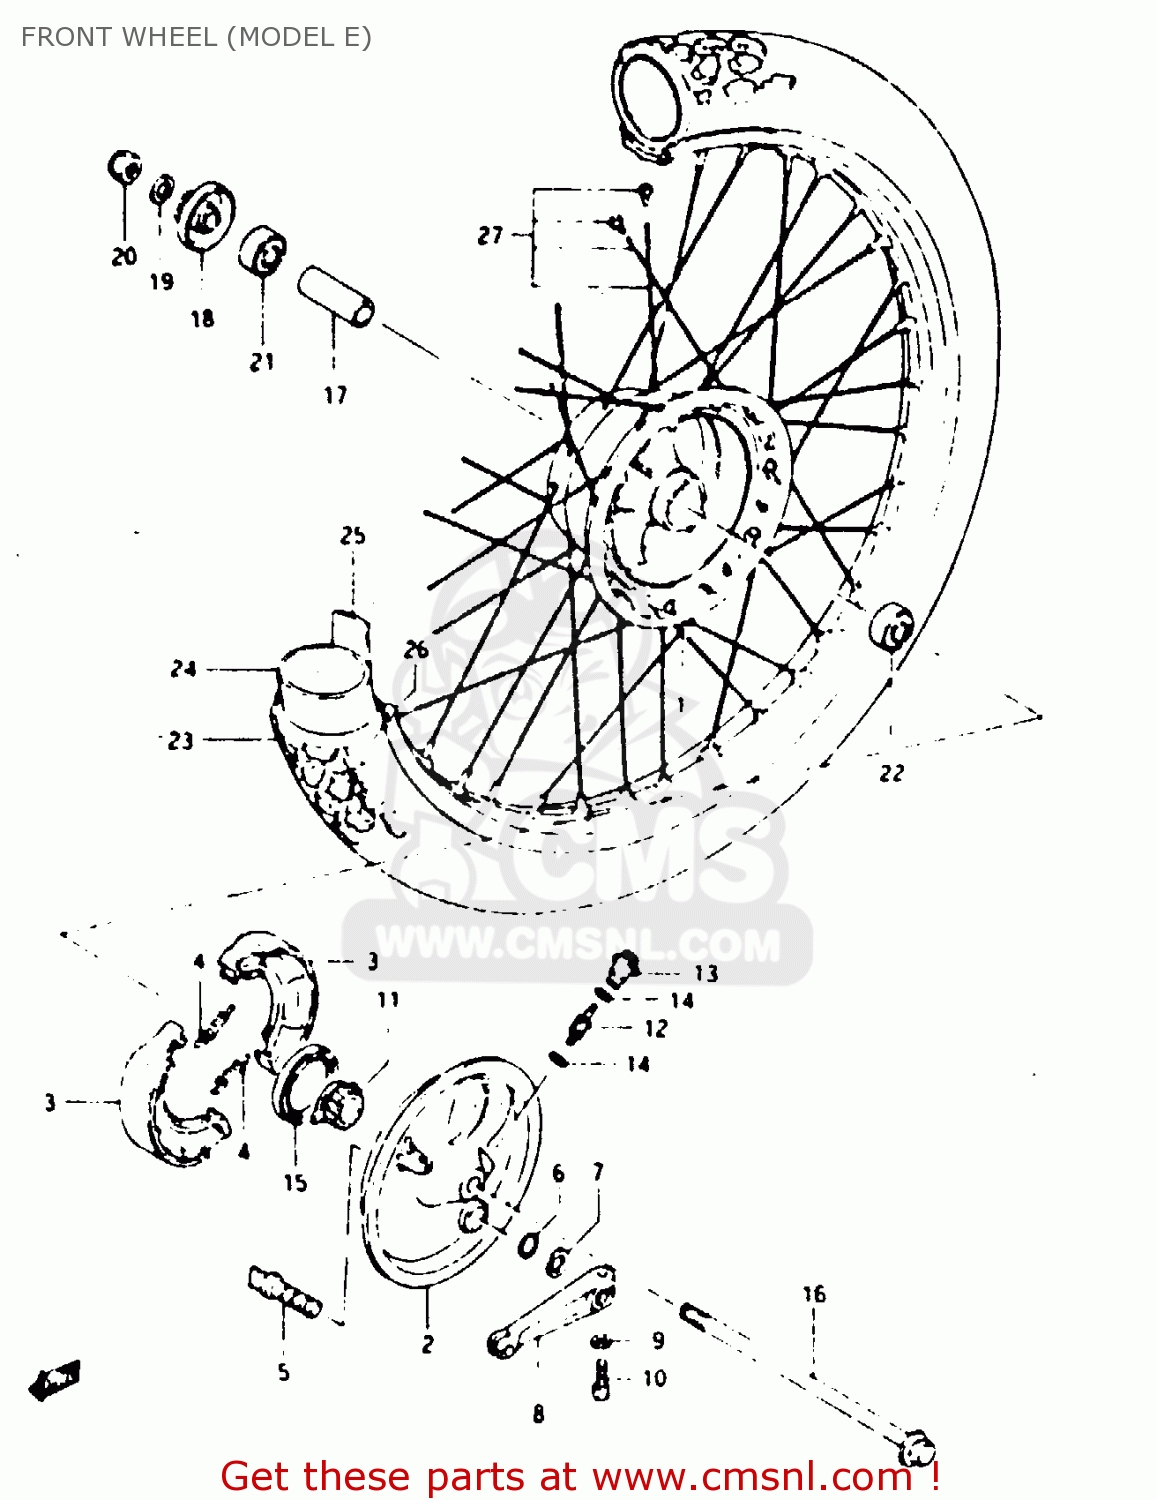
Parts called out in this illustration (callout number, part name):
1	HUB, WHEEL
2	PANEL
3	SHOE,BRAKE
4	SPRING(L:34)
5	CAM, BRAKE
6	O RING(D:2.5,ID:11.4)
7	WASHER(12.5X20X1)
8	LEVER, BRAKE CAM
9	WASHER
10	BOLT
11	GEAR,SPEEDOMETER(NT:26)
12	PINION,SPEEDOMETER(NT:9)
13	BUSH,SPEEDOMETER PINION OUTER
14	WASHER (5.1X9X0.4)
15	OIL SEAL (43X58X7)
16	AXLE,FRONT
17	SPACER, HUB BEARING
18	SPACER, AXLE RH
19	WASHER
20	NUT (12MM)
21	BEARING
22	BEARING, RH
23	TIRE, FRONT (80/80-21) BS
24	TUBE
25	PROTECTOR,WHEEL,INNER
26	RIM, WHEEL (1.60*21)
27	SPOKE SET, FRONT
